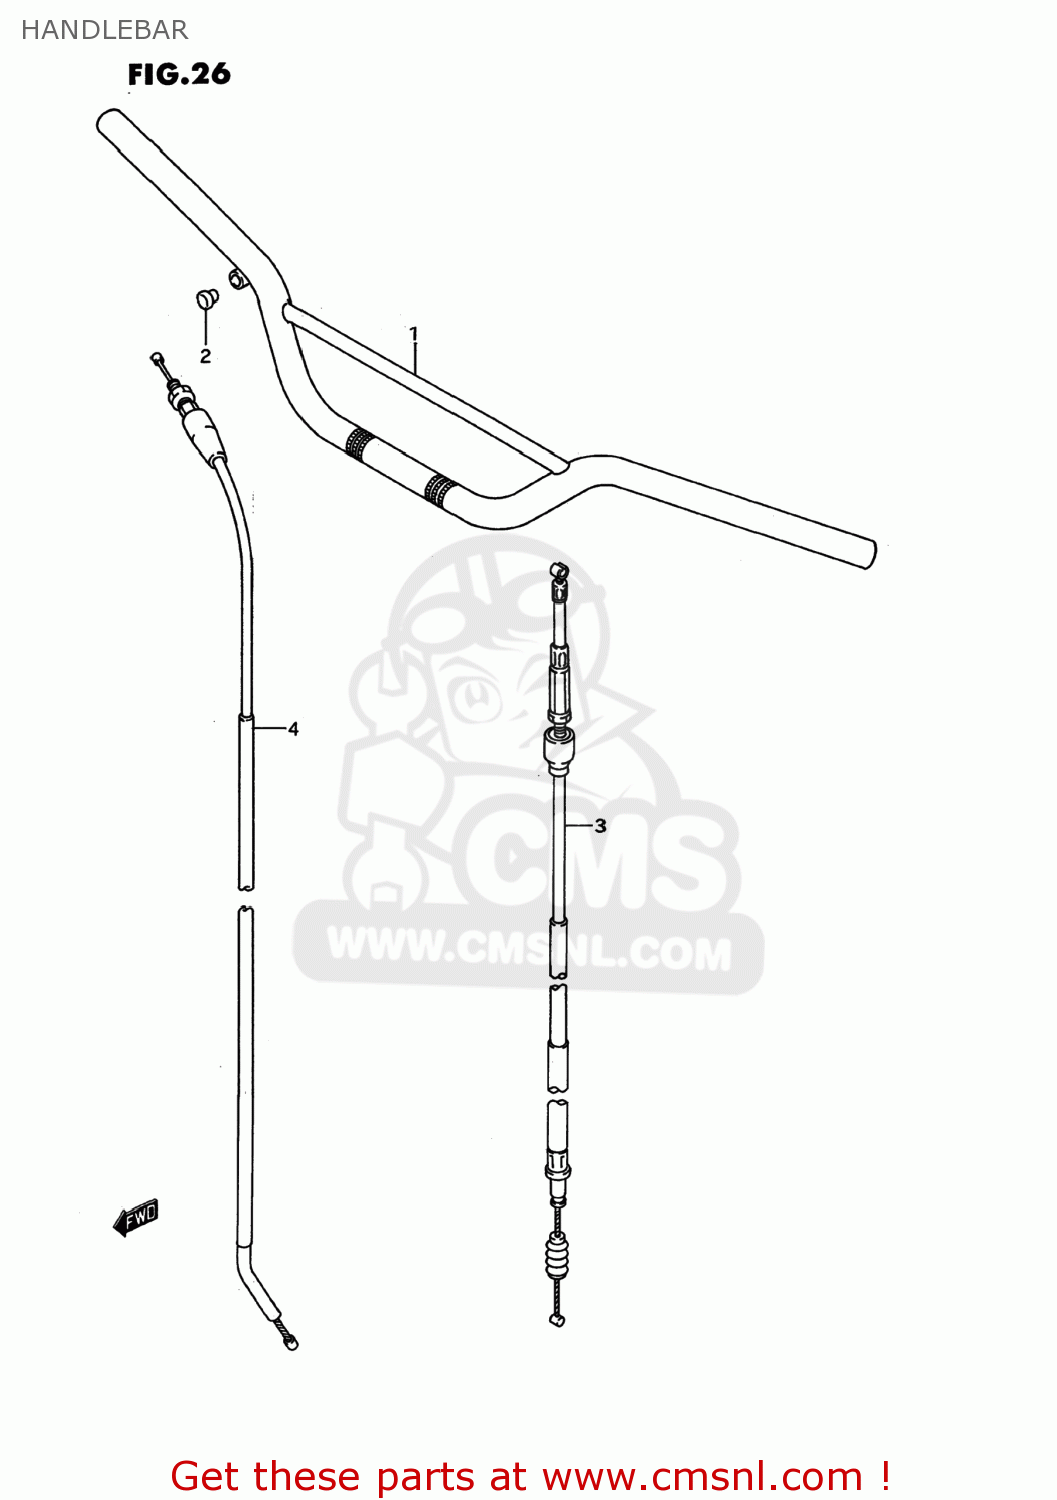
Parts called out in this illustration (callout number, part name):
1	HANDLEBAR
2	CAP(OD:14)
3	CABLE ASSEMBLY,CLUTCH
4	CABLE ASSEMBLY,THROTTLE
